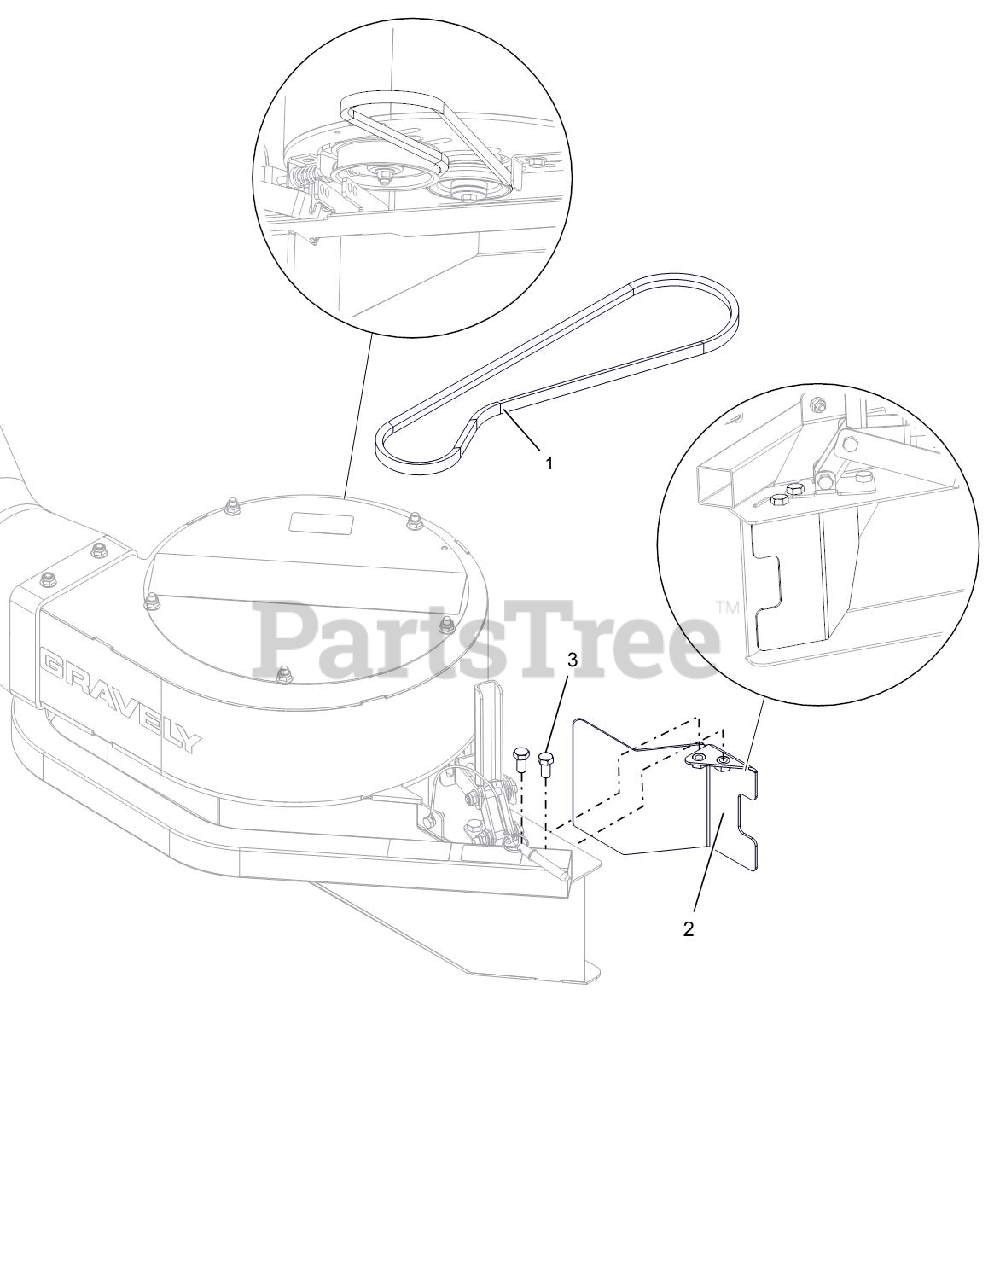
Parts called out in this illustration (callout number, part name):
1	V-BELT, 4L WRAPPED CLUTCHING
2	60" FRT BLOWER BAFFLE WMT -BLK
3	@BLT-HEX .38-16X.75 GR5 YWZC
